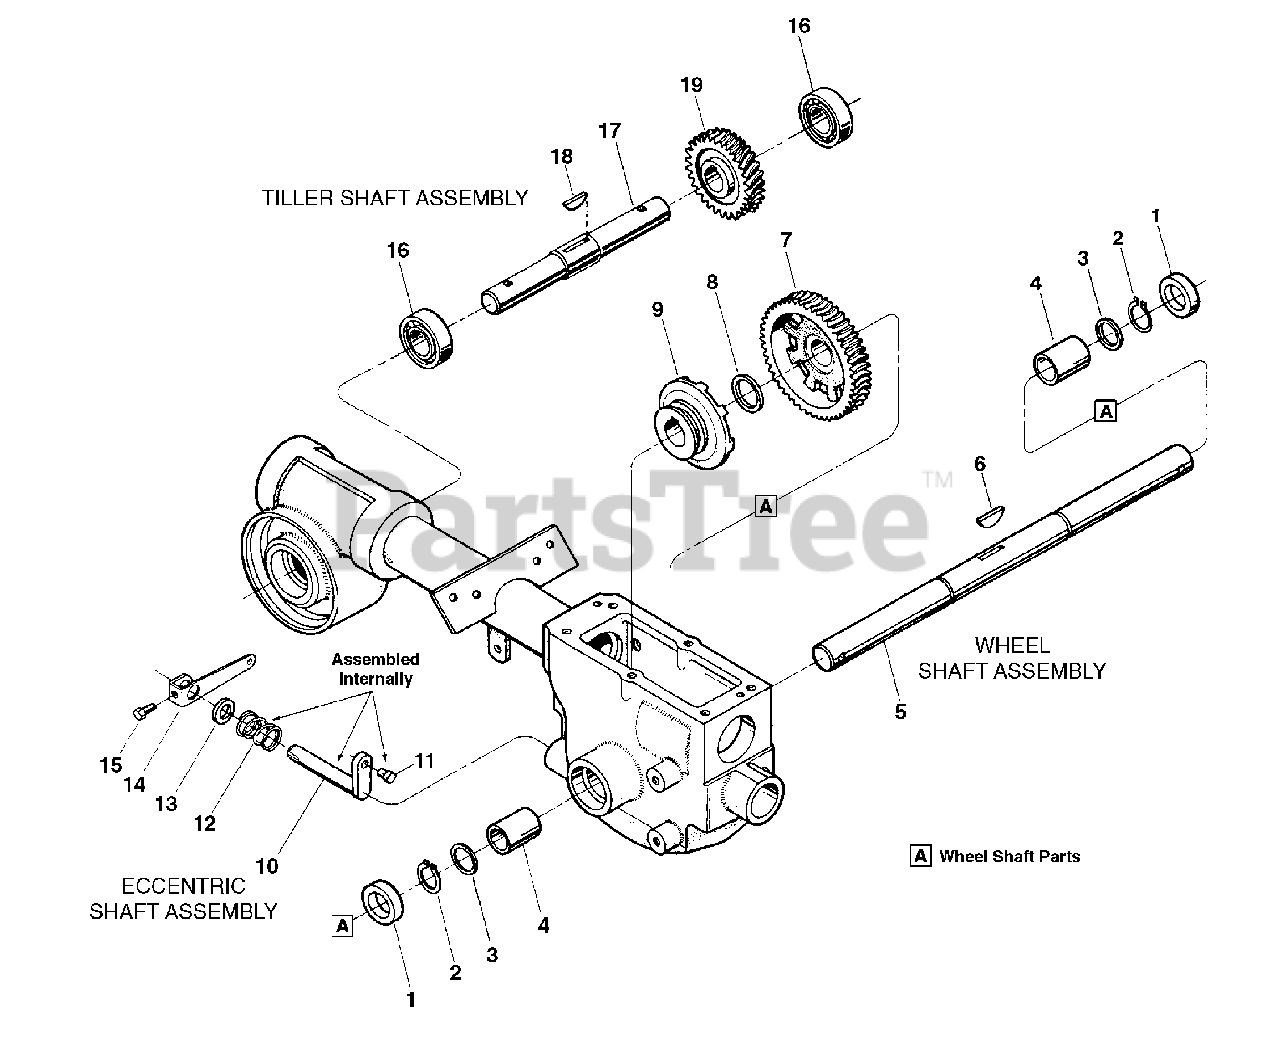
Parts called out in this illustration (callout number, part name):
1	Oil Seal
2	Ring-retaining, heavy-duty, ext.
3	Shim-1-1/64 I.D., .062 thick
4	Bushing
5	Wheel Shaft (axle)-
6	Key-hi-pro (1/4 x 1-5/16)
7	Gear-wheel drive (worm gear)
8	Shim-1.016 I.D. x 1.468 O.D. x .062 thick
9	Clutch-wheel drive, cast iron
10	Eccentric Shaft-wheel clutch
11	Pin-eccentric shaft
12	Spring
13	Oil Seal-eccentric shaft
14	Lever-eccentric shaft
15	Screw-hex hd., 1/4-20 x 1/2
16	Ball Bearing-
17	Tiller Shaft-
18	Key-woodruff, 1/4 x 1-1/4
19	Worm Gear-bronze, tiller drive
